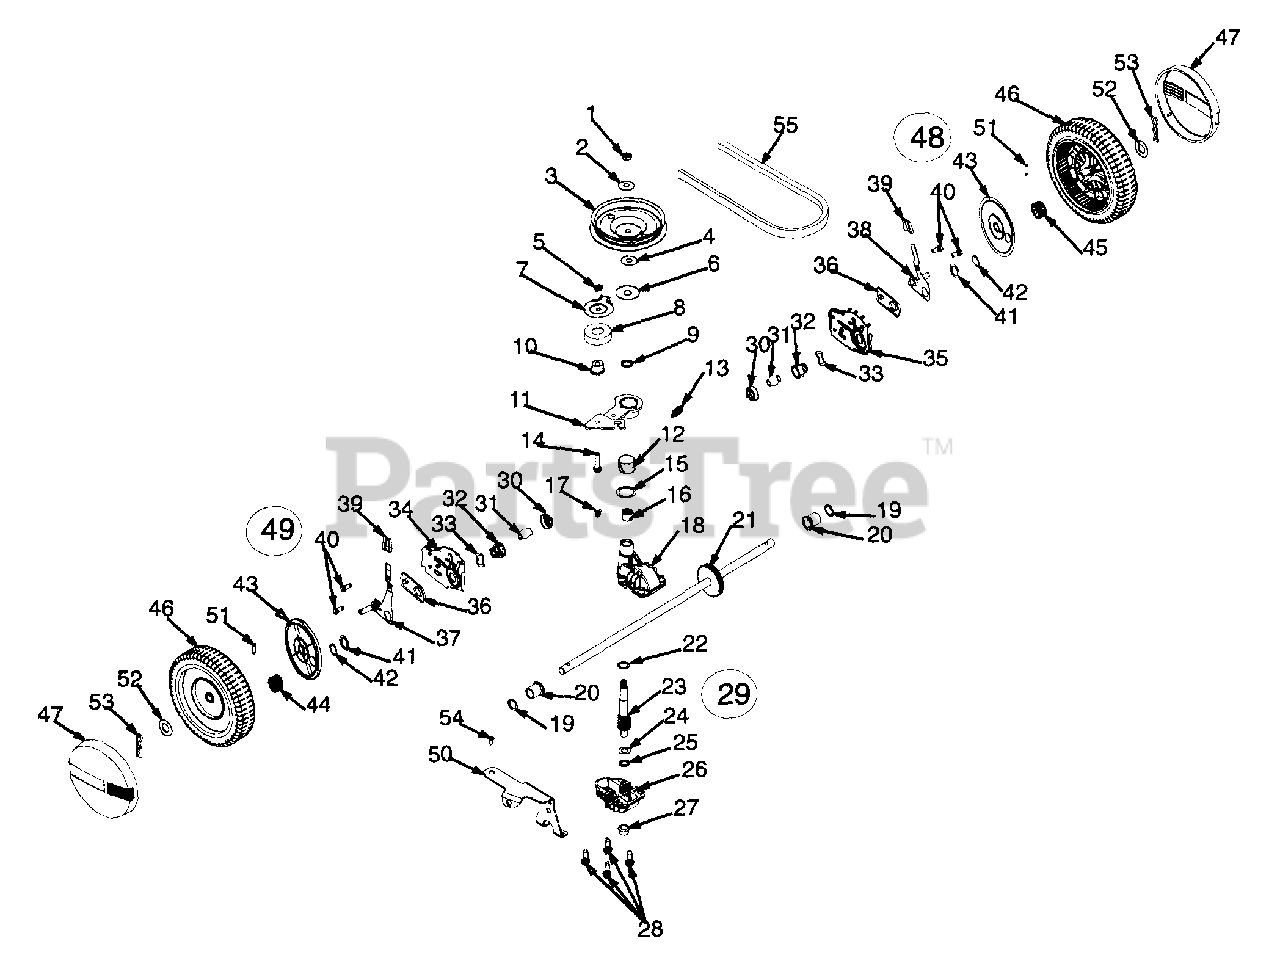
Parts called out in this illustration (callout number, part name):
1	Hex Jam Nut 5/16-24
2	Bell Wash .325 x .930 x .045
3	Pulley
4	Bell Wash .325 x .930 x .045
5	Hex Nut 1/4 - 28 Lock
6	Flat Wash .442 x 1.38 x .060
7	Belt Keeper
8	Ball Bearing
9	Oil Seal
10	Flange Spacer
11	Idler Bracket Ass'y
12	Bearing Sleeve
13	Wash: Flat: .504 x .700 x .030
14	Hex Cap Screw 1/4-28 x 1.00 Gr. 5
15	Flat Washer .865 x 1.145 x .030
16	Needle Bearing .438 x .625 x .500
17	Plug 1/4 x .437
18	Housing Asm: Upper:
19	Seal: Oil: .500 x .687 x .094
20	Flange Bearing .503 x .689 x .792
21	Output Shaft
22	Flat Washer .504 x .700 x .030
23	Pinion Shaft 10T.
24	Thrust Washer .375 x .70 x .030
25	Thrust Washer .388 x .625 x .062
26	Housing:Lwr:
27	Flange Bearing .378 x .531 x .370
28	Hex Screw w/Wash 1/4-20 x .750
29	Transmission-Complete
30	Bearing Retainer
31	Bearing Sleeve .50 I.D.
32	Bearing Support
33	Wave Washer 1.5 x 1.0 x .029
37	Front Lever R.H
38	Front Lever L.H.
39	Knob
40	Hex Cap Screw 3/8-16 x .75
41	Washer DD 1.5" O.D.
42	Snap Ring 1.0 Dia.
43	Wheel Dust Cap
44	Gear 14T RH Fwd
45	Gear 14T LH Fwd
46	Whl 8 x 1.75 Disk Bar Gray Sleeve S
47	Hubcap: Whl: Radial Spoke Grey
48	Height Adj. Complete RH
49	Height Adj. Complete LH
50	Cable Idler Bracket
51	Dowel Pin
52	Flat Washer 1/2 x 1.00 x .063
53	Cotter Pin .08 x 1.42
54	Screw, Shoulder .375 x .25AB: 1/4-20 Thd.
55	"V"-Belt
